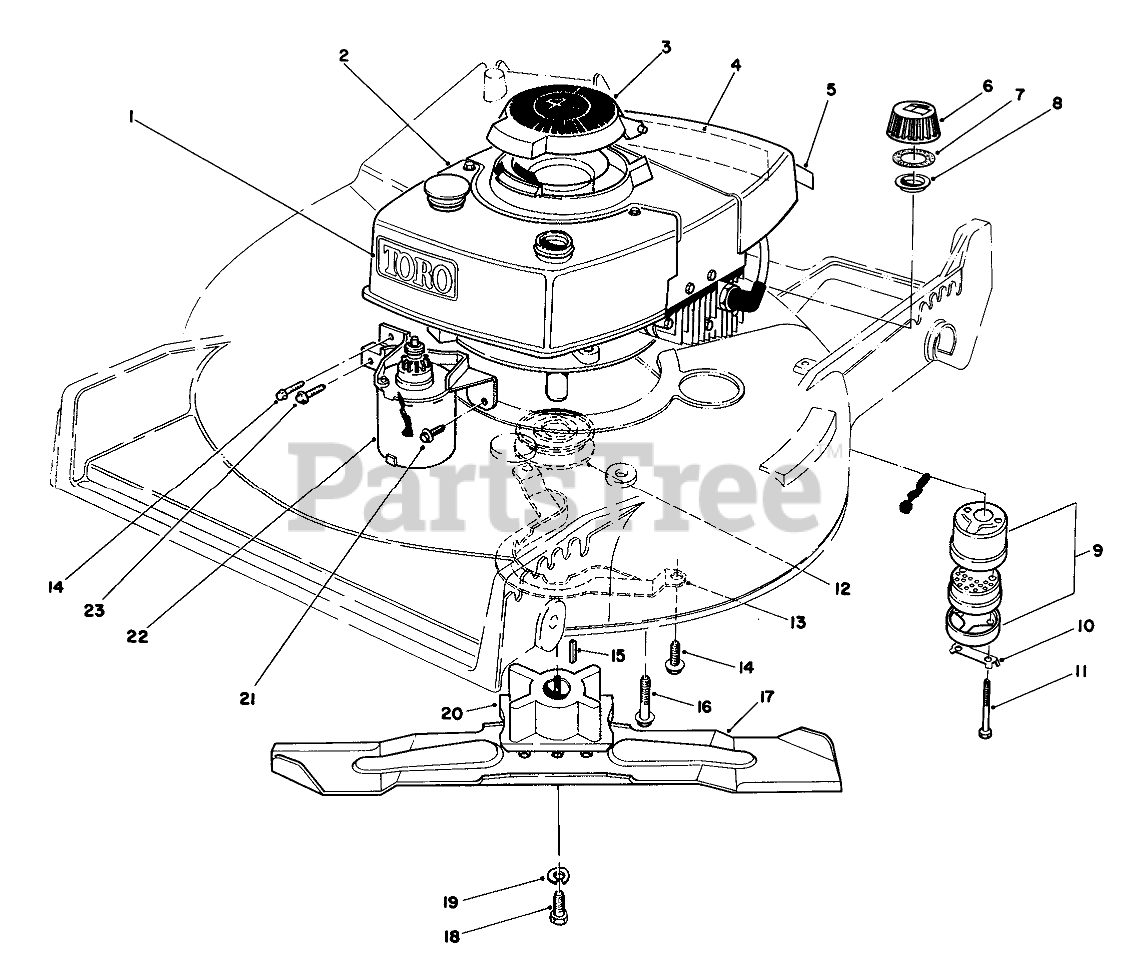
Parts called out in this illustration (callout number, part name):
1	Decal Tow
2	Engine
3	COVER ASM
4	Decal Maintenance
5	Decal-Primer Bulb
6	Gas Cap (Incl. Ref. #7 & 8)
7	GASKET
8	GAS CAP BAFFLE
9	Muffler Assembly (Incl. Ref. #10 & 11)
10	CLIP - LOCKING
11	SCREW-HH
12	Pulley
13	BELT GUIDE
14	Screw
15	KEY-SQUARE
16	3/8-16 X 2 CAPSCREW
17	BLADE-21in
18	SCREW-BLADE
19	WASHER-LOCK
20	BLADE RETAINER(DEEP)
21	SCREW
22	STARTER MOTOR ASM
23	SCREW AND WASHER ASM
